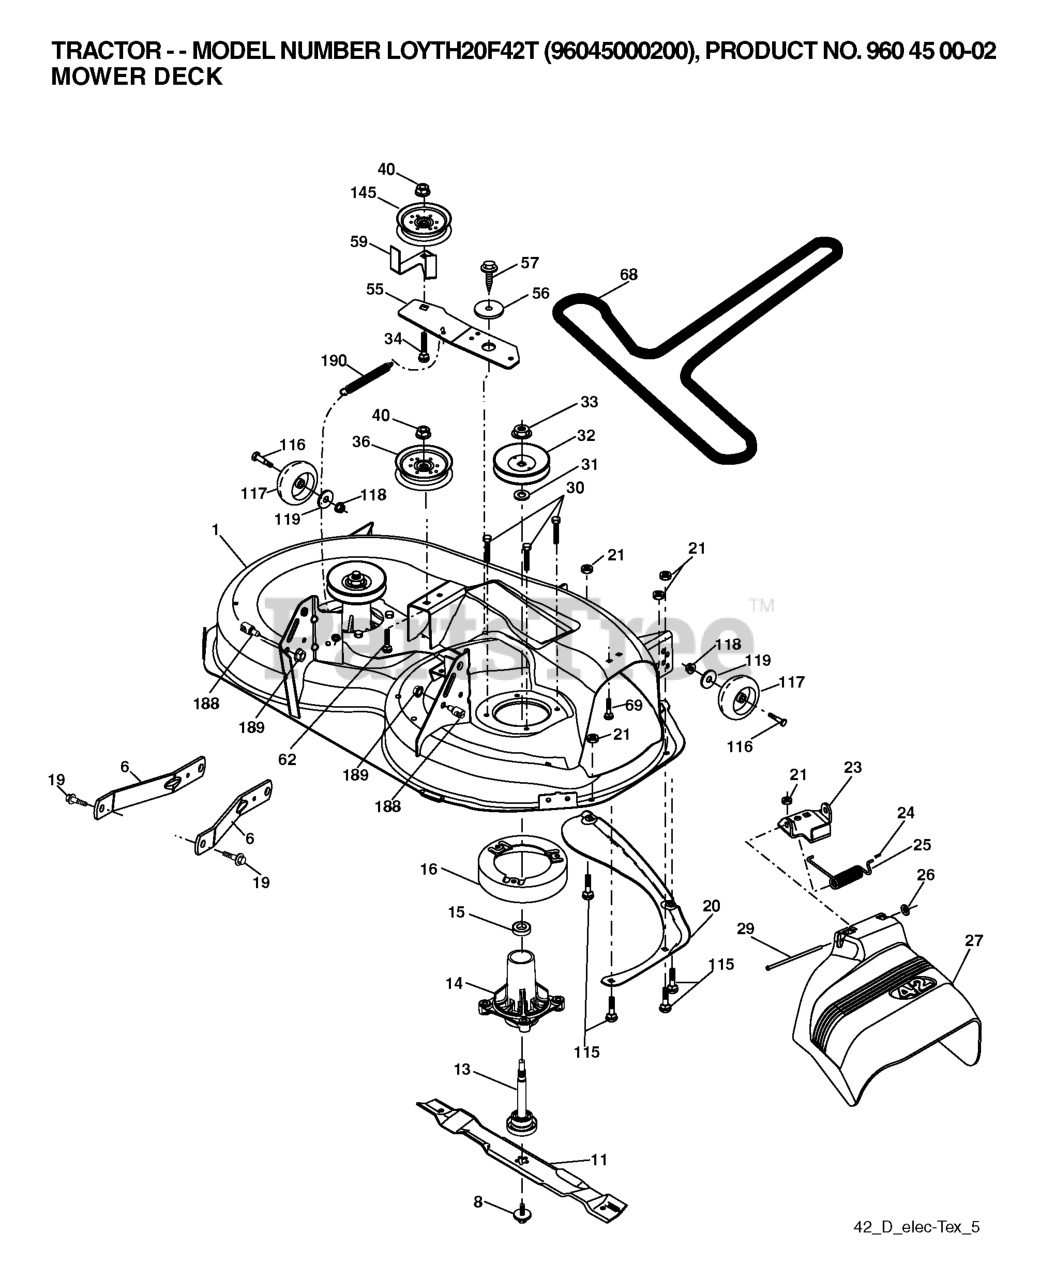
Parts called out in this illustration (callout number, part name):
1	DECK.WELDMENT.42"PAINT
6	ARM.SUSPENSION.MOWER.R
8	BOLT.WASHER.ASM.7/16-2
11	42" HI-LIFT BLADE
13	SHAFT.ASM.MDRL.N/GREASE.38
14	RP.HOUSING.MANDREL.4PT.
16	STRIPPER.MANDREL.ROUND.BLACK
19	BOLT.SHOULDER
20	BAFFLE.VORTEX
21	LOCKNUT
23	BRKT.DEFLECTOR.38"2005+
24	CAP-SLEEVE LT
25	SPRING.TORSION.DEFLECT
26	NUT PUSH M
27	SHIELD.DEFLECTOR.MOWER.42"BLAC
29	ROD.HINGE
30	SCREW, WASHER HEAD
31	WASHER.SPACER.MANDREL
32	PULLEY MANDREL
33	NUT.FLANGE.LOCK.TOP
34	BOLT.3/8-16X1.50
36	PULLEY.IDLER.2006
40	NUT LOCK FLG 3/8-16 UNC
56	SPACER.RETAINER
57	SCREW 3/8-16X1
59	GUARD TUV IDLER
68	BELT V SECONDARY
69	BOLT
115	BOLT.CARR.5/16-18X5/8.SHORT
116	SHOULDER BOLT
117	RP WHEEL. GUAGE RALLY
118	LOCKNUT
119	WASHER.5/16.FLAT.STE.STD.
145	PULLEY.IDLER.FLAT
188	STUD.FASTNER.W/ANTI-ROTATE
189	NUT LOCK HEX FLANGE 5/16-18
190	SPRING.MOWER.DRIVE.ELECTRIC
